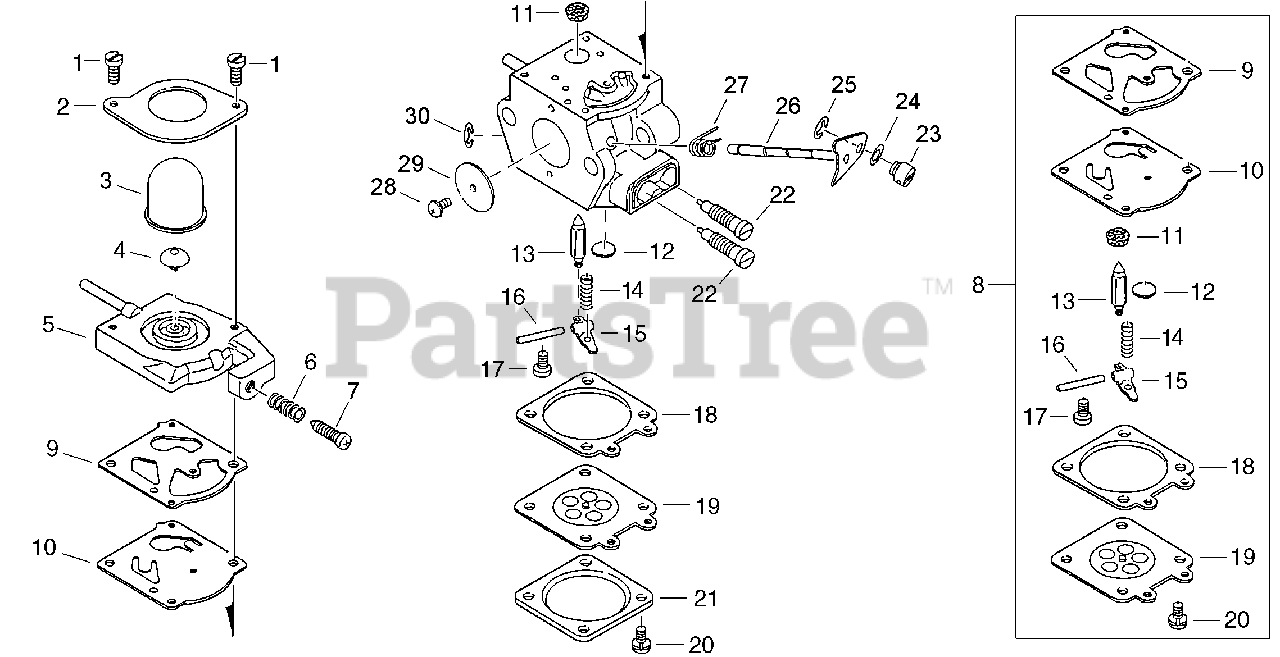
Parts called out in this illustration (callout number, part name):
2	RETAINER, PURGE BULB
3	BULB, PURGE
4	VALVE, CHECK
5	COVER, FUEL PUMP
6	SPRING, IDLE ADJUST
7	SCREW, IDLE ADJUST
8	REPAIR KIT, CARBURETOR
9	GASKET, FUEL PUMP
10	DIAPHRAGM, FUEL PUMP
11	SCREEN, FUEL INLET
12	PLUG, WELCH
13	VALVE, INLET NEEDLE
14	SPRING, METERING LEVER
15	LEVER, METERING
16	PIN, METERING LEVER
17	SCREW, METERING LEVER PIN
18	GASKET, METERING DIAPHRAGM
19	DIAPHRAGM, METERING
21	COVER, METERING DIAPHRAGM
22	NEEDLE, MIXTURE
26	SHAFT, THROTTLE
27	SPRING, THROTTLE RETURN
29	VALVE, THROTTLE
